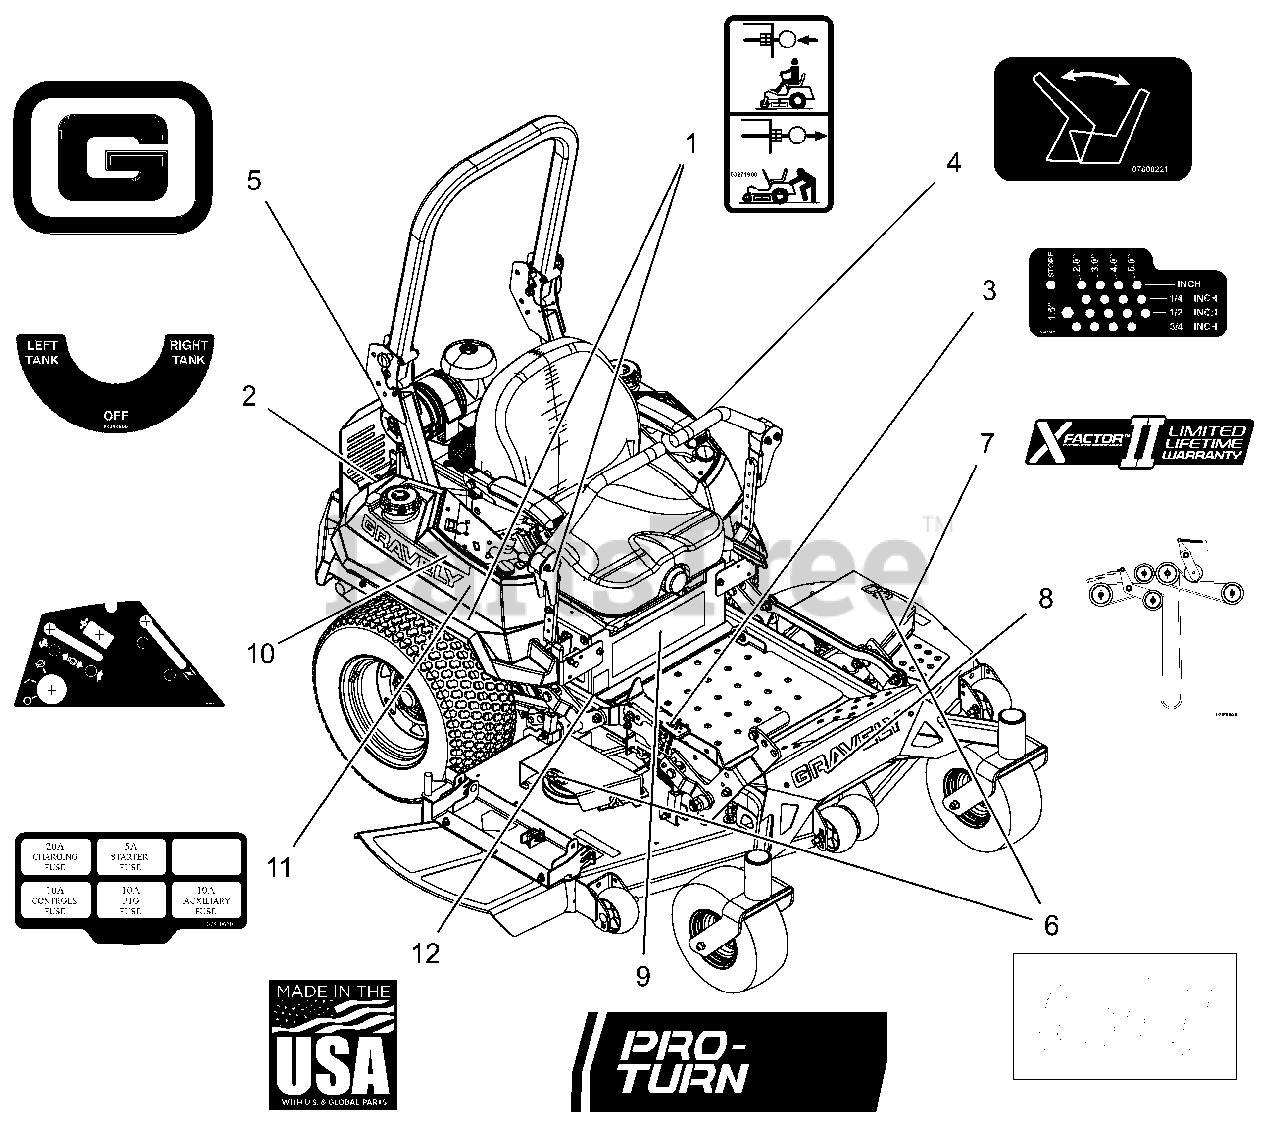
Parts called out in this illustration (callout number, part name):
1	DECAL, TRANSMISSION DISCONNECT
2	DECAL, FUEL VALVE
3	DECAL, HEIGHT OF CUT
4	DECAL - SEAT RELEASE
5	DECAL, GRAVELY BRAND
6	DECAL, 60"
7	DECAL, X-FACTOR DECK
8	DCL,BELT ROUTE-RH BK-SIDE IDLR
9	DECAL, PRO-TURN 160
10	DECAL, NON-EFI CONTROL PANEL
11	DECAL, FUSE BLOCK
12	DECAL, MADE IN USA
